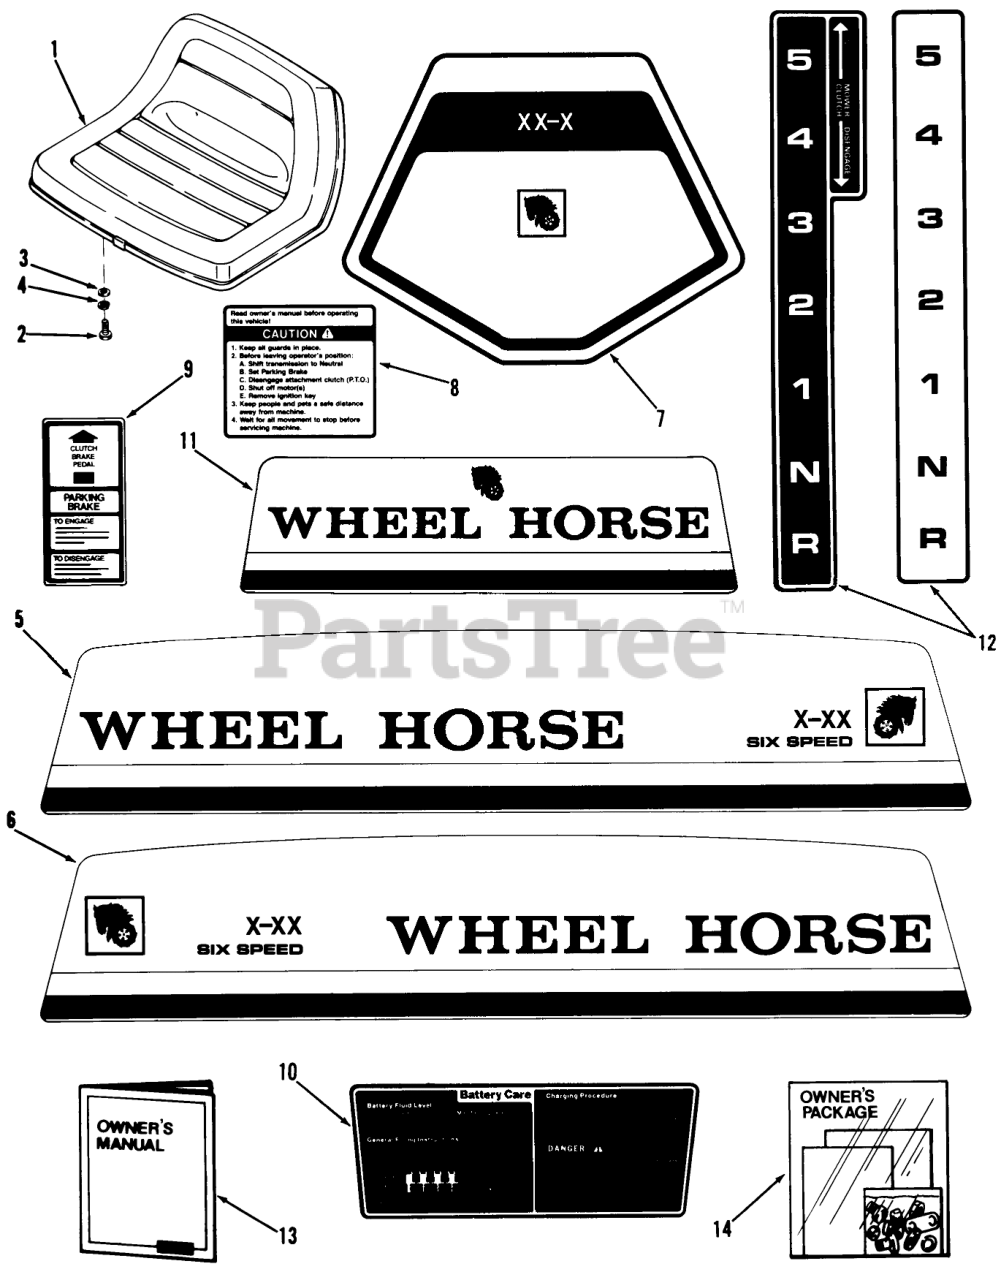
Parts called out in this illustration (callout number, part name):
1	Seat
1	ASSY-SEAT
2	Bolt
2	H H C S
3	WASHER 5/16 SAE
4	Lockwasher
5	Decal-Hood A-81 RH
5	DECAL-SIDE A-111
5	Decal-Hood A-51 RH
5	Decal-Hood E-81 R.H.
6	Decal-Hood A-81 LH
6	Rubber Plate
6	Decal-Hood A-51 LH
6	Decal-Hood E-81 L.H.
7	Decal-Shroud A-81
7	Decal-Shroud A-111
7	A-51 SHROUD DECAL
7	Decal-Shroud E-81
8	DECAL-CAUTION
9	Decal-Parking Brake
10	DECAL-BATTERY CARE
11	Decal-Rear Hood E-81
12	Decal-Shift and Mower A-51, 81
12	Decal-Shift E-81
13	Owner-s Manual
14	New Rider Loose Parts Pkg A-81E
14	New Rider Loose Parts Pkg A-111
14	New Rider Loose Parts Pkg A-51
14	New Rider Loose Parts Pkg A-81R
14	New Rider Loose Parts Pkg E-81
